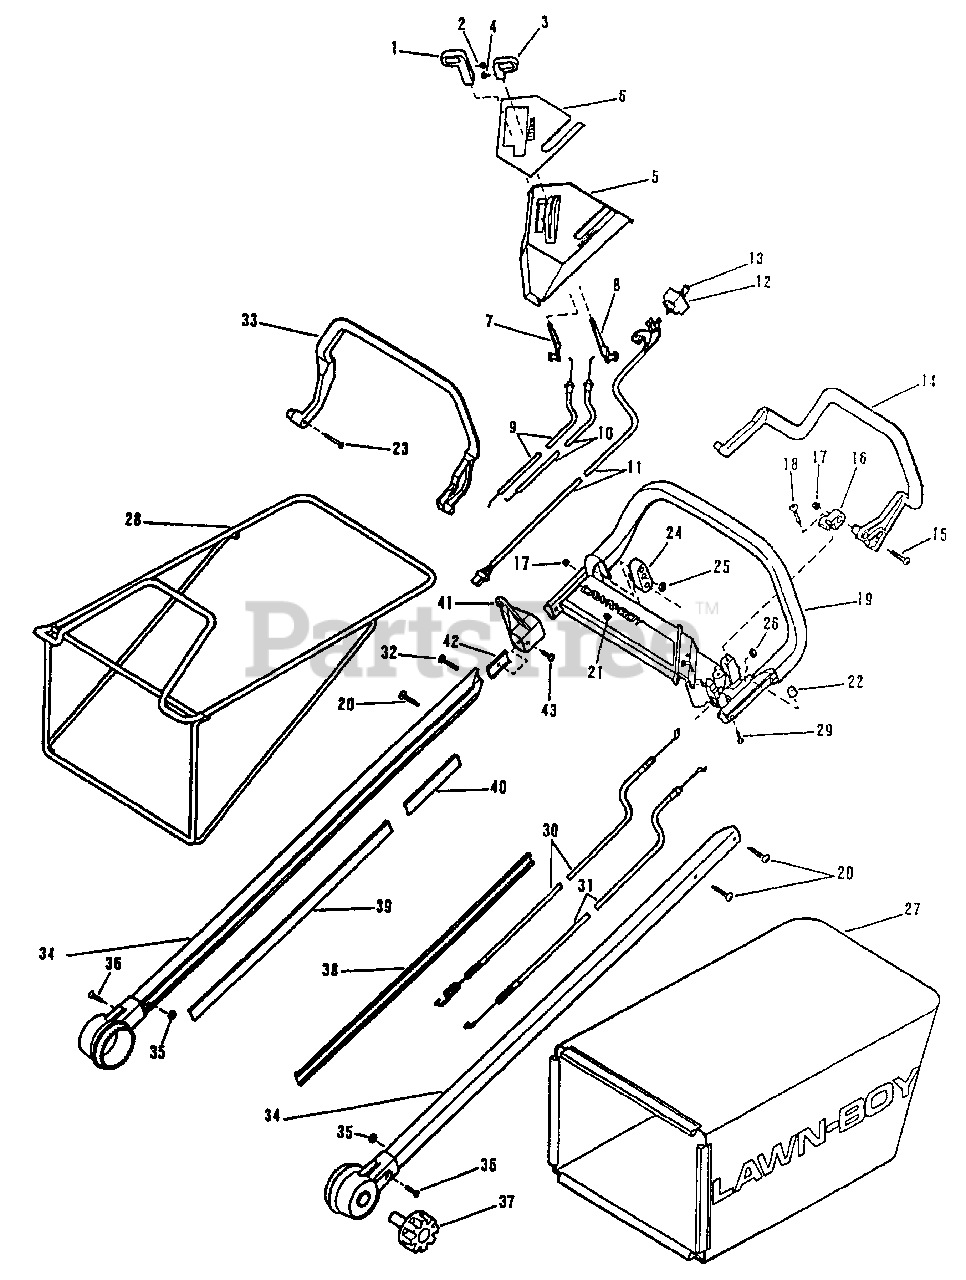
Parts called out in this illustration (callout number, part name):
1	Knob Assembly-Gear Select
2	Set Screw
3	Knob Assembly-Throttle
4	Set Screw
5	Upper Cover Assy (EMRB)
6	Plate
7	Gear Select Lever
8	Throttle Lever
9	Cable Assembly-Gear Select
10	Cable Assembly-Throttle
11	Wire Harness
12	Switch Assembly
13	Ignition Key
14	Self-propelled Bail
15	Screw
16	Bail Pivot
17	Nut
18	Screw
19	Handle and Decal Assembly
20	Screw-Thread Forming
21	Decal-Lawn-Boy
22	Bumper
23	Screw
24	Bail Block
25	Nut
26	Nut-Self-propelled Cable
27	Rear Grass Bag
28	Frame
29	Screw
30	Cable Assembly-Self-propelled
31	Cable Assembly-Engine Brake
32	Screw
33	Engine Brake Bail
34	Handle Knuckle and Extrusion
35	Nut
36	Screw
37	Knob-Handle Mounting
38	Handle Insert-Cable Side
39	Handle Insert
40	Handle Insert
41	Rope Guide
42	Nut Plate
43	Screw
